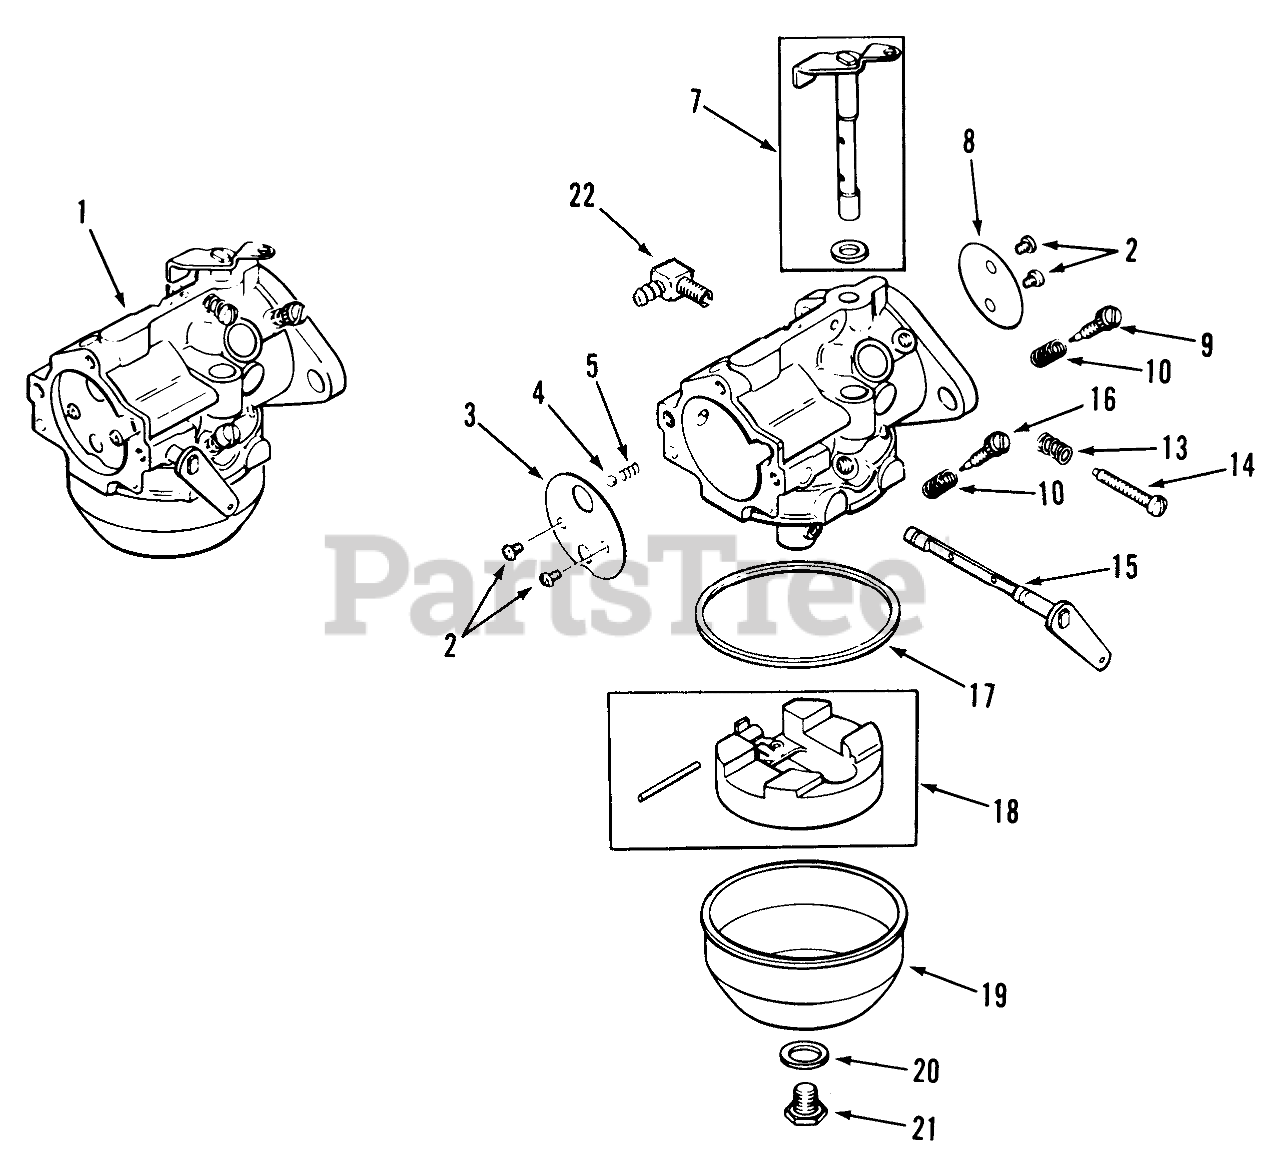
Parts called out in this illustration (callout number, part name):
1	Carburetor Assembly (Includes 5 thru 8) 310, 312
2	Screw
3	Choke Plate
5	Spring
7	Shaft w/Lever & Seal
8	Plate-Throttle
9	Idle Fuel Adj. Needle
10	Spacer
13	Adj. Spring
14	Idle Speed Adj. Screw
15	Choke Shaft
16	Main-Needle
17	Gasket
18	Float Kit
19	Bowl-Fuel
20	Gasket
21	Screw
